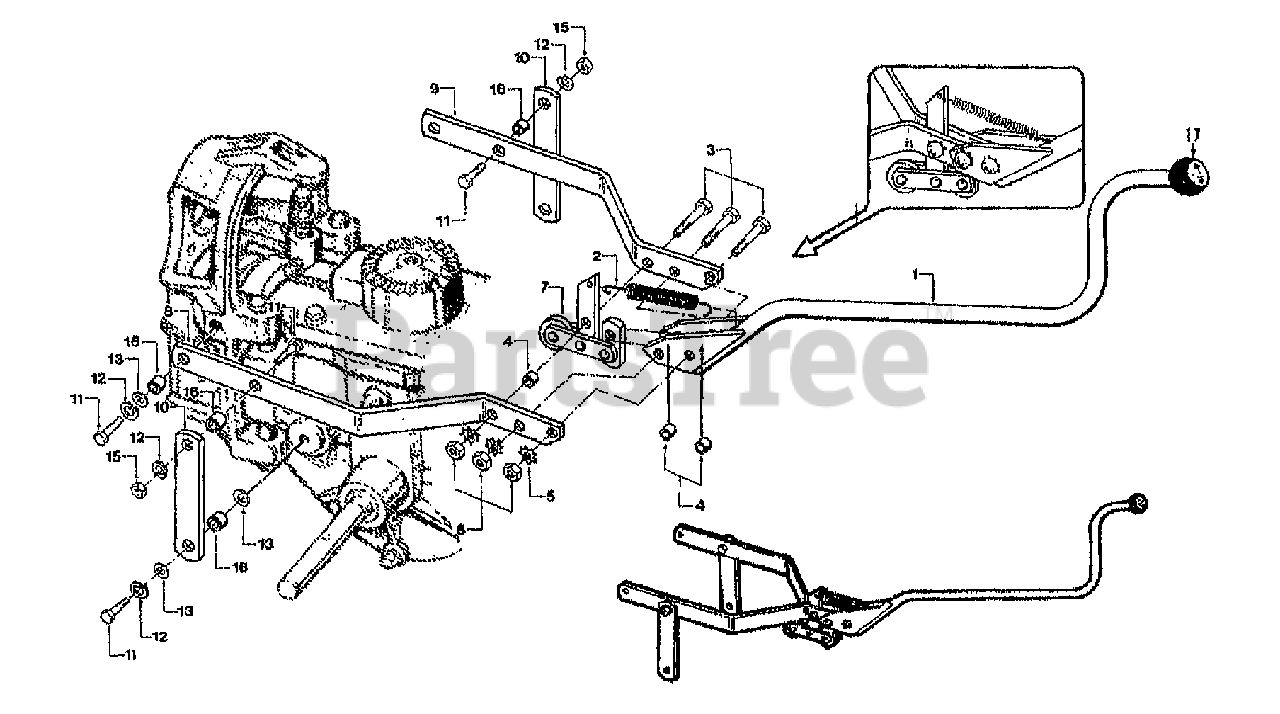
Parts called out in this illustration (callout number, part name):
1	ASSM-FOR/REV LEVER (INCL. KNOB W/DECAL)
2	SPRING-.436 X 3.25
3	SCR-HH 5/16-18X1.5 G5 ZP
4	BUSHING-.5X.316X.375 PM
5	WASHER-LK .312 EXT TOOTH
6	NUT-HEX 5/16-18 ZP
7	ASSM-ROLLER PAINT
8	YOKE-LH RED
9	YOKE-RH RED
10	YOKE-RED 2164
11	SCR-HH 3/8-16X1.0 G5 ZP
12	WASHER-LK .375 @ DEPL
13	WASHER-FLAT 3/8 SAE
14	THIS REF. NO. NOT USED
15	NUT-HEX 3/8-16 ZP
16	BUSHING-.5X.375X.3 (.300")
17	KNOB - NOT AVAIL. SEPARATELY. SEE REF. NO. 1
